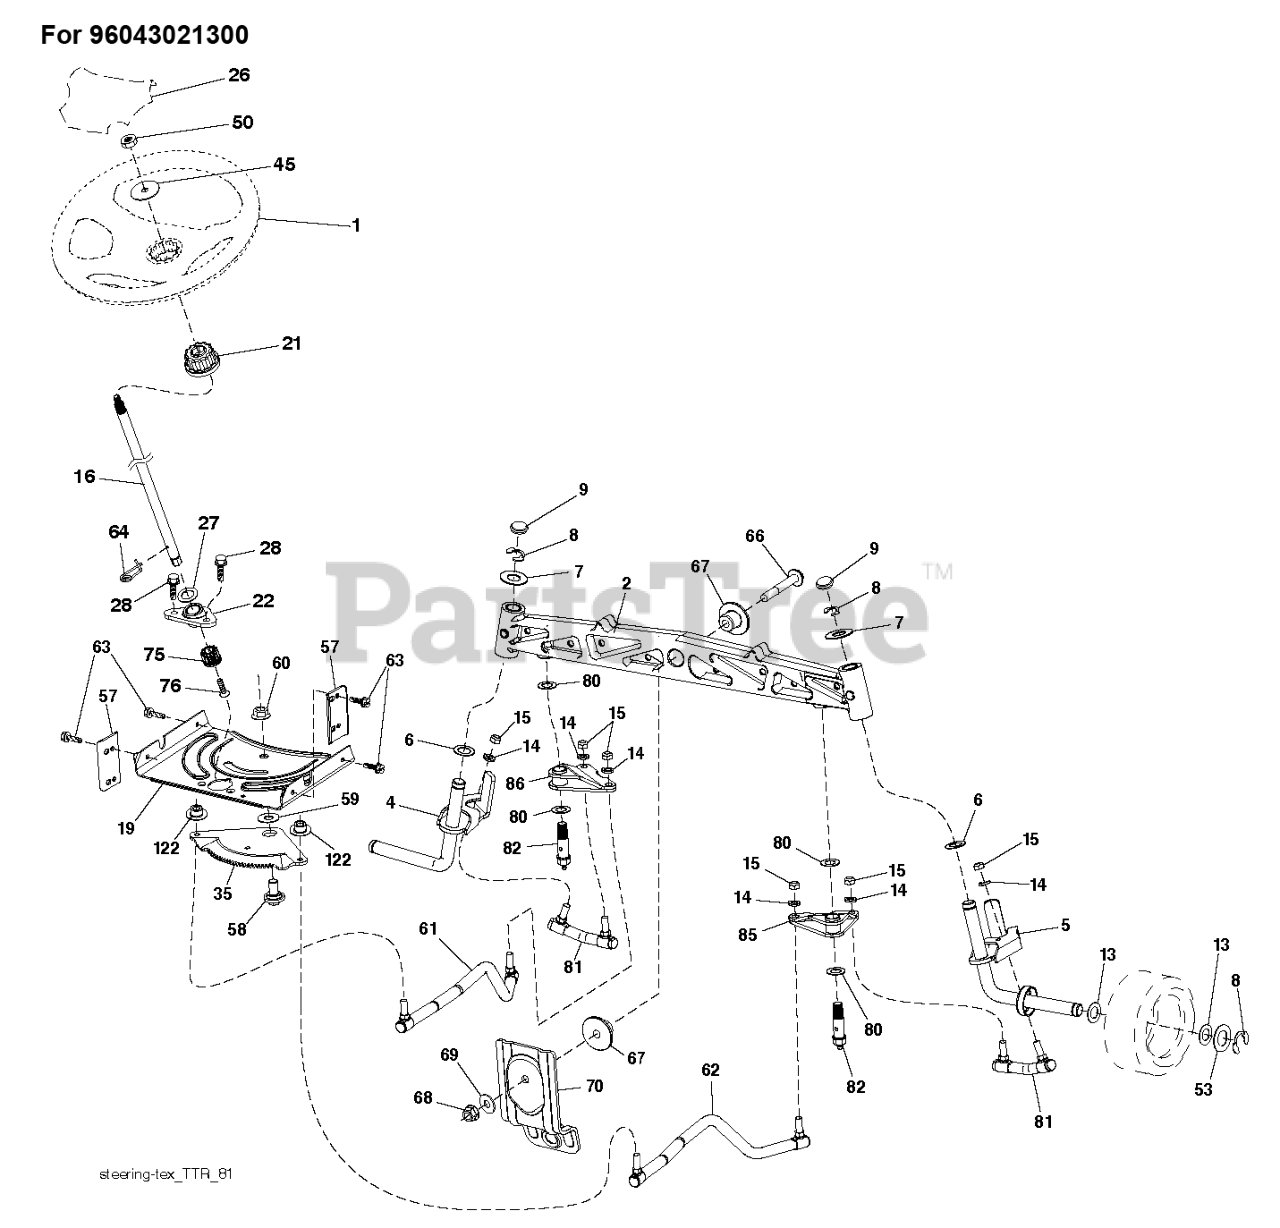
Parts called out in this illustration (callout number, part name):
1	WHEEL.STEER.HUSQ.SR.498.OVMLD
2	SUBASM.AXLE.CAST.NZTR.
4	WELDMENT.SPINDLE.LH.15.NZTR
5	WELDMENT.SPINDLE.RH.15.NZTR
6	WASHER THRUST
9	CAP.SPINDLE.BLACK
15	NUT CROWNLOCK 3/8-24
16	KIT.SRVC.STEERINGSHAFT.2HISHFT
19	PLATE.STEER.DDL.NLT/NG
21	KIT.SRVC.STEERINGSHAFT.ADAPTER
22	KIT.SRVC.STEERINGSHAFT.LWRBSHG
26	INSERT.CAP.WHL.STRG.HUSQ.PREM
28	SCREW, 3/8-16X3/4
35	GEAR.SECTOR.TEX.NZTR
45	WASHER.3/8ID.2-3/8OD.12GA.PLTD
50	NUT.HEX.FLANGE.3/8-16.LOCKNUT
53	WASHER.HARDENED
57	BRACKET.UPSTOP.TEX
58	BOLT.SHOULDER.SECTOR.P
59	WASHER.THURST.SECTOR.S
60	NUT FLANGE LOCK 5/8-11
61	SUBASM.LINK.DRAG.LH.NZTR
62	SUBASM.LINK.DRAG.RH.NZTR
63	SCREW
64	RETAINER.CLIP.SPRING.S
66	BOLT HEX FGHD 7/16-14 X 3 SERR
67	BUSHING.PM.FRONT AXLE
68	NUT.LOCK.FLANGE.7/16
69	WASHER.1.5X.505X.118
70	BRACKET.FRT.DECK.SUSP.RR.MT431
75	PINION.ZINC PLATED
76	SCREW HEAD SOCKET LRVB
80	THRUST WASHER
82	SUBASM;PIVOT;BOLT;NZTR
85	SUBASM.PIVOT.RH.NZTR
86	SUBASM.PIVOT.LH.NZTR
122	CAP.GEAR.SECTOR.TEX
